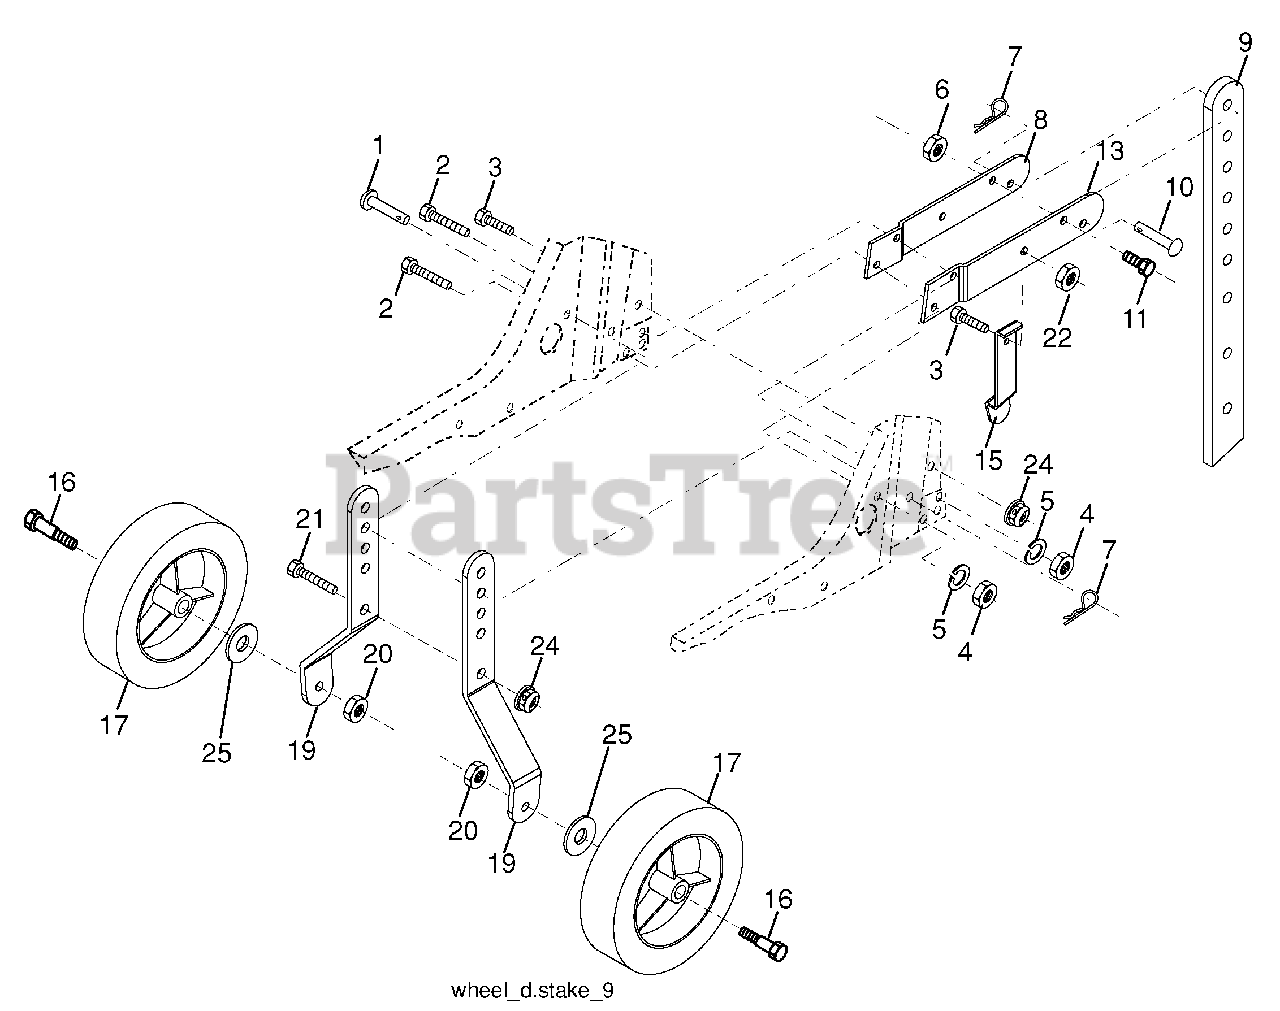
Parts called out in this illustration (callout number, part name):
1	Pin, Clevis
2	Bolt, Hex Head 5/16-18 x 1-1/4
3	Bolt, Hex Head 5/16-18 x 3/4
4	Nut, Hex 5/16-18
5	Washer, Lock 5/16
6	Locknut, Washer Insert 3/8-16
7	Clip, Hairpin
8	Support, Depth Stake, R.H.
9	Stake, Depth
10	Pin, Clevis
11	Bolt, Hex Head 3/8-16 x 1-3/4
13	Support, Depth Stake, L.H.
15	Spring, Stake
16	Bolt, Shoulder
17	Wheel
19	Bracket, Wheel
20	Nut, Hex, Crownlock 3/8-16
21	Bolt, Hex Head 5/16-18 x 1
22	Locknut, Washer Insert 5/16-18
24	Nut, Hex, Flangelock
25	Washer, 17/32 x 7/8 x 16 Ga.
